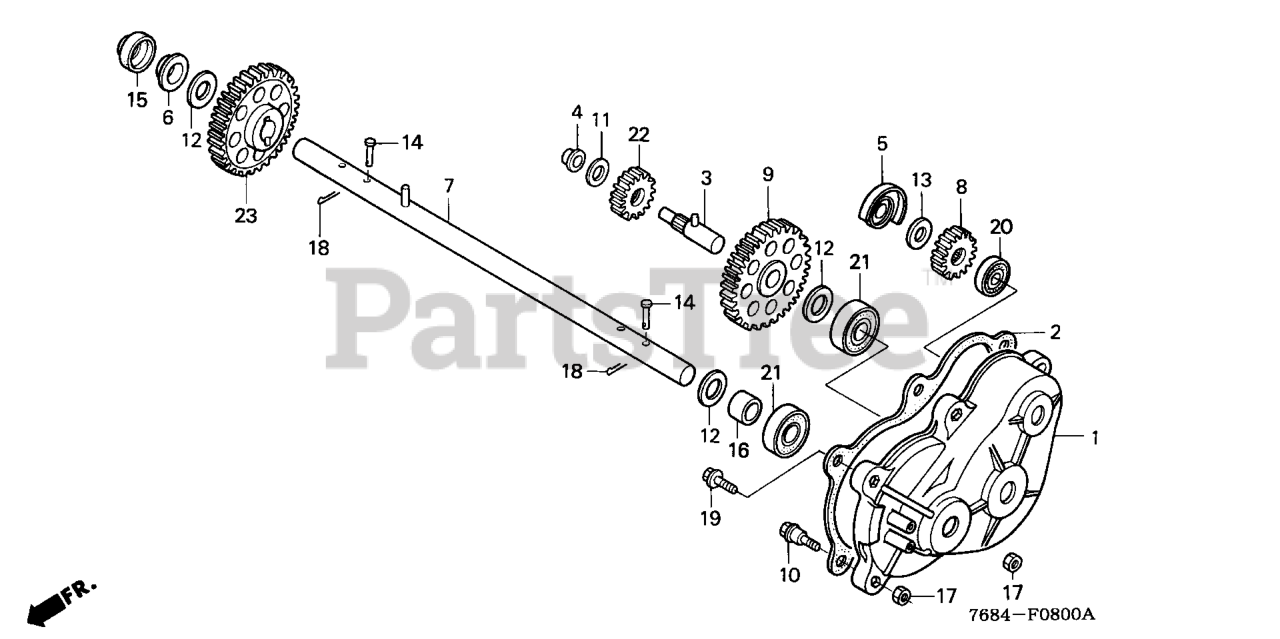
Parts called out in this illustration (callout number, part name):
1	CASE, R. TRANSMISSION
2	GASKET, TRANSMISSION CASE
3	COUNTERSHAFT
4	BUSH, COUNTERSHAFT
5	BUSH, CROSS SHAFT
6	BUSH, FINAL SHAFT
7	GEAR SET, FINAL
7	SHAFT, WHEEL
8	GEAR, DRIVE (19T)
9	GEAR, DRIVEN (48T)
10	BOLT, TRANSMISSION SETTING
11	WASHER, THRUST (12MM)
12	WASHER, DIFFERENTIAL GEAR
13	WASHER, THRUST (15X24X2)
15	DUST SEAL (20X34X7.5)
16	COLLAR, WHEEL SHAFT
17	NUT, HEX. (6MM)
18	PIN, SPLIT (3.0X25)
18	PIN, COTTER (3.0X45)
19	BOLT, FLANGE (6X18)
20	BEARING, RADIAL BALL (6002UU)
21	BEARING, RADIAL BALL (6004UU)
22	GEAR, DRIVE (19T)
23	GEAR, DRIVEN (48T)
